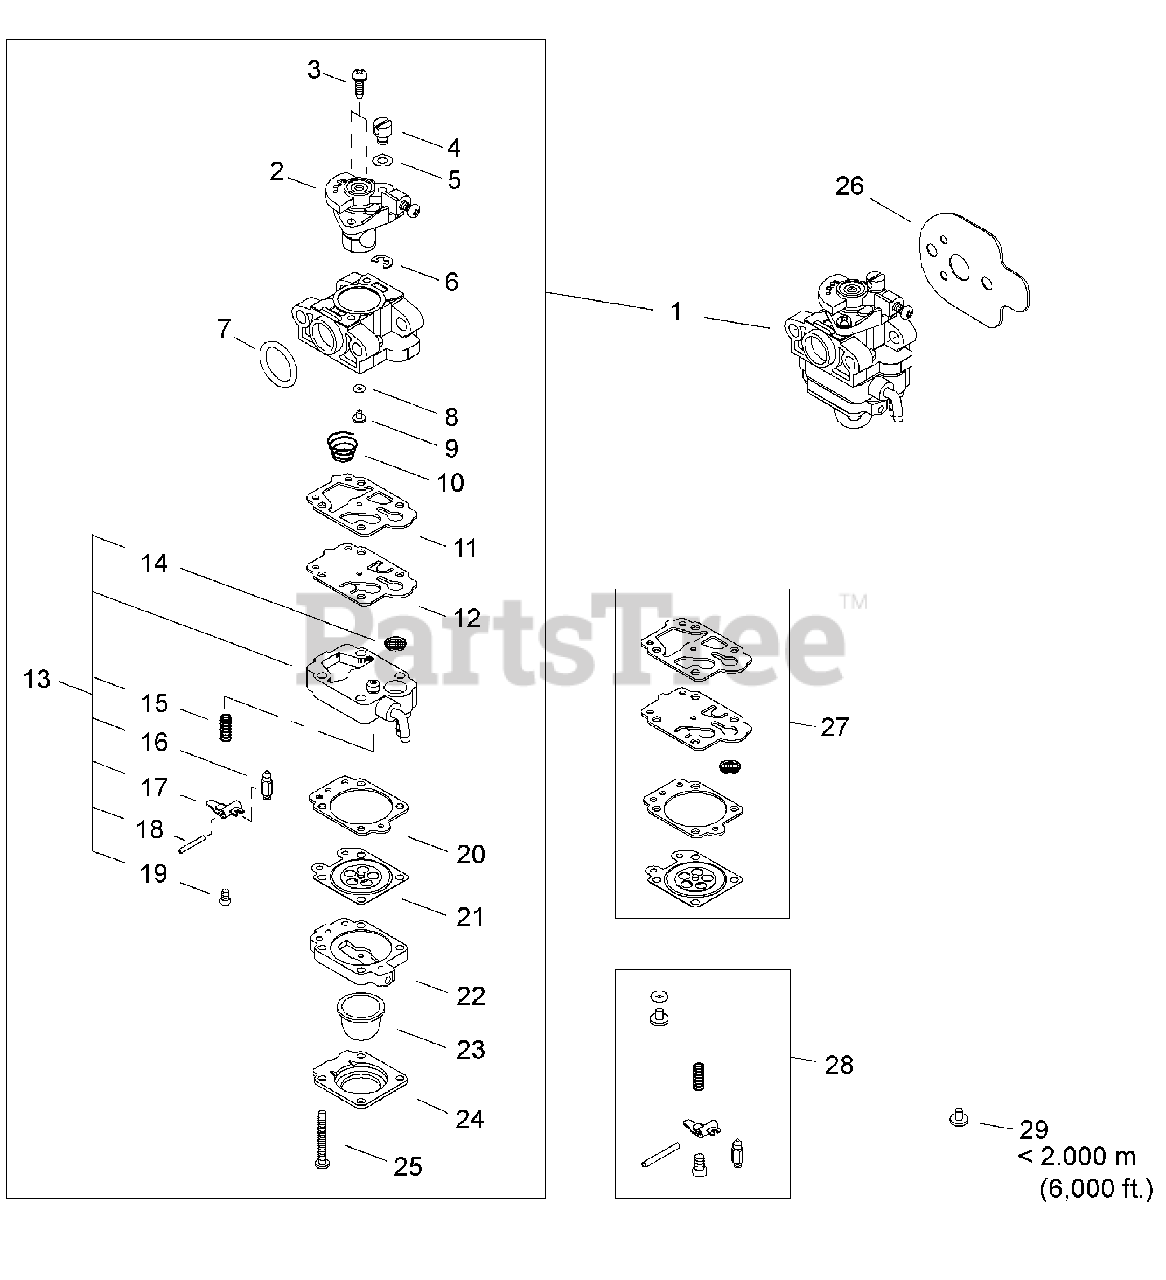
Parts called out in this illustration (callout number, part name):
1	CARBURETOR
2	VALVE ASSY, THROTTLE
3	SCREW, THROTTLE COLLAR
4	SWIVEL
5	WASHER
6	E-RING
7	O-RING 15
8	O-RING
9	JET, MAIN #40
11	GASKET, PUMP
12	DIAPHRAGM, PUMP
13	BODY ASSY, PUMP
14	SCREEN, FUEL INLET
15	SPRING, METERING LEVER
16	VALVE, INLET NEEDLE
17	LEVER, METERING
18	PIN, METERING LEVER
19	SCREW
20	GASKET, METERING DIAPHRAGM
21	DIAPHRAGM, METERING
22	BODY ASSY, PURGE
23	BULB, PURGE
24	RETAINER, PURGE BULB
25	SCREW
26	GASKET, INTAKE
27	GASKET / DIAPHRAGM KIT
28	VALVE KIT, INLET NEEDLE
29	JET, MAIN #38
